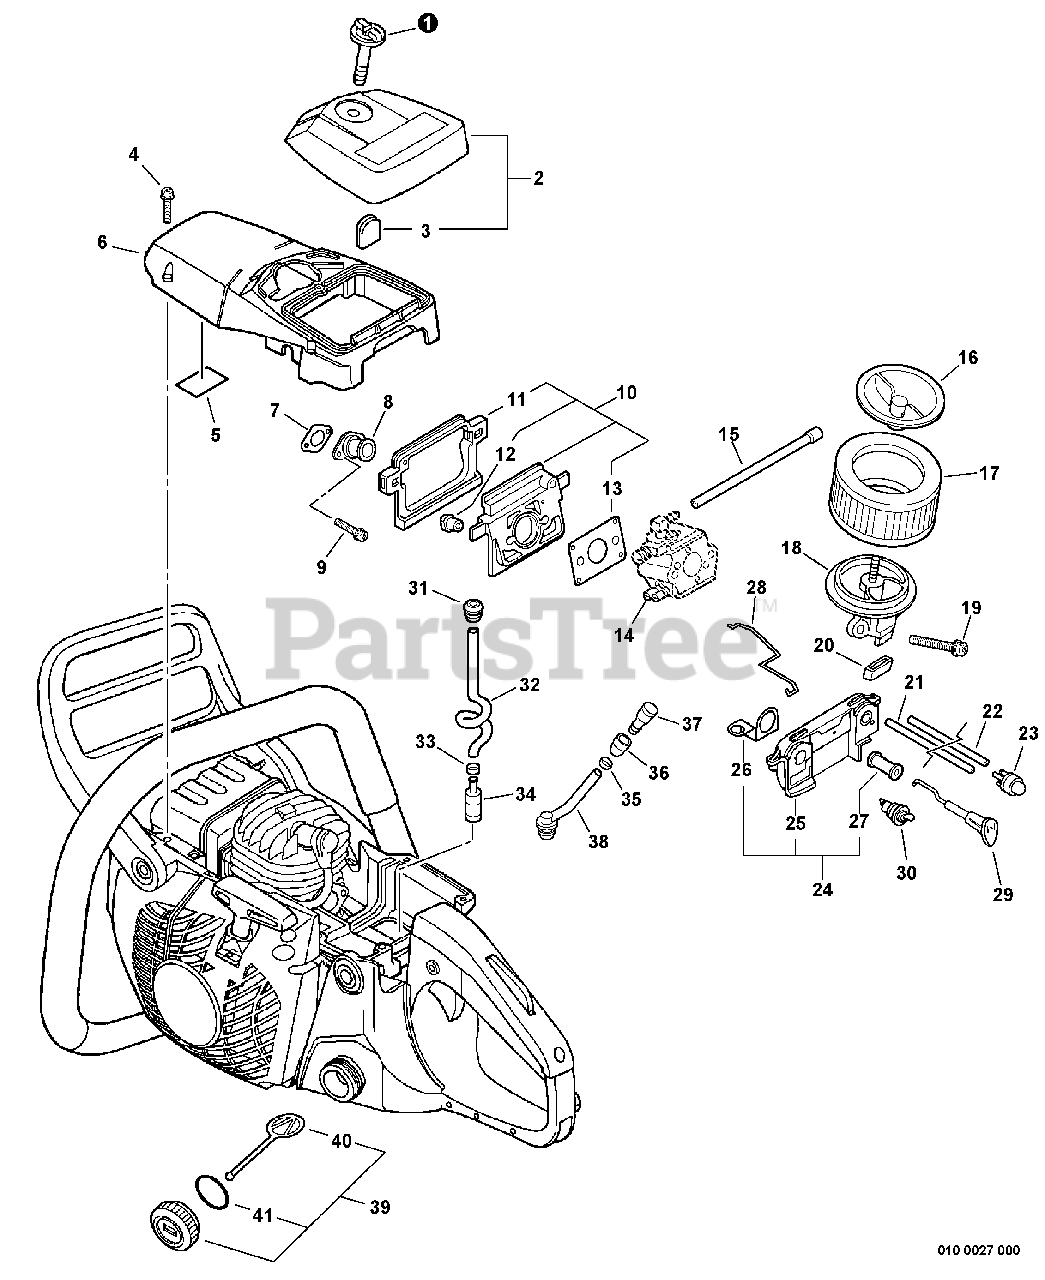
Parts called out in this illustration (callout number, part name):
1	THUMBSCREW
2	AIR FILTER COVER ASSY - ORANGE
4	SCREW - 5X25
5	DEFLECTOR, HEAT
6	COVER, ENGINE
7	GASKET, INTAKE
8	ADAPTOR, INTAKE
9	SCREW - 5X12
10	INSULATOR KIT
11	CUSHION
13	GASKET, INTAKE
14	CARBURETOR
15	PIPE - IMPULSE
16	COVER, AIR FILTER
17	FILTER, AIR
18	ADAPTOR, INTAKE
19	SCREW - 5X50
21	PIPE - 3X5X140 -- BLACK
22	PIPE - 3X5X140 -- BLACK
23	PUMP, PURGE
24	SWITCH BRACKET KIT
25	BRACKET, SWITCH
26	TERMINAL - GROUND
27	GROMMET
28	ROD, THROTTLE
29	ROD, CHOKE
30	IGNITION SWITCH ASSY
31	GROMMET
32	PIPE, FUEL - SPIRAL
33	CLIP - 6.5
34	FILTER, FUEL
35	CLIP - 6.5
36	COVER, VENT
37	VENT, FUEL TANK
38	PIPE - VENT
39	CAP ASSY - BLACK
40	CONNECTOR, CAP
41	O-RING - 22
